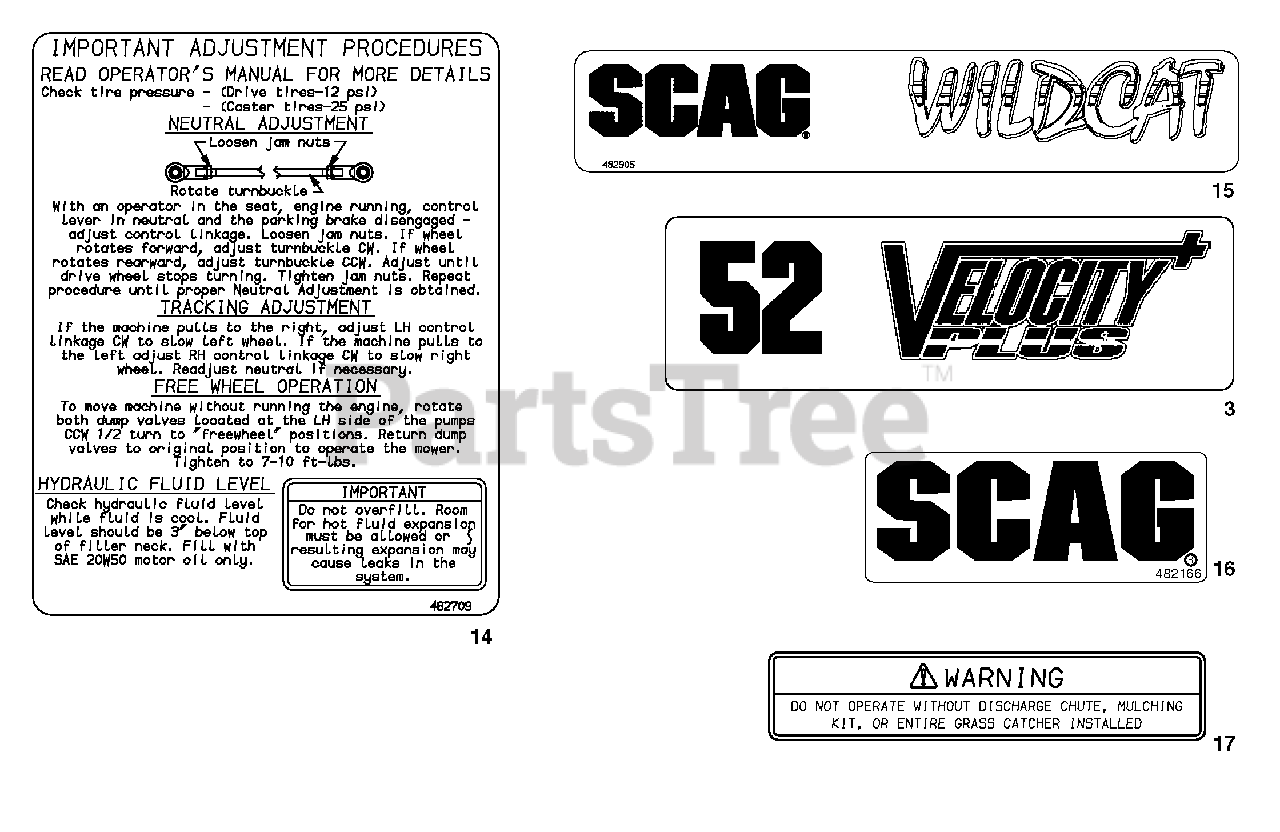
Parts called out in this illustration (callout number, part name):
3	Decal, 52V
14	Decal, Seat Support
15	Decal, Rear Bumper
16	Decal, Front Footplate
17	Decal, Discharge Chute
